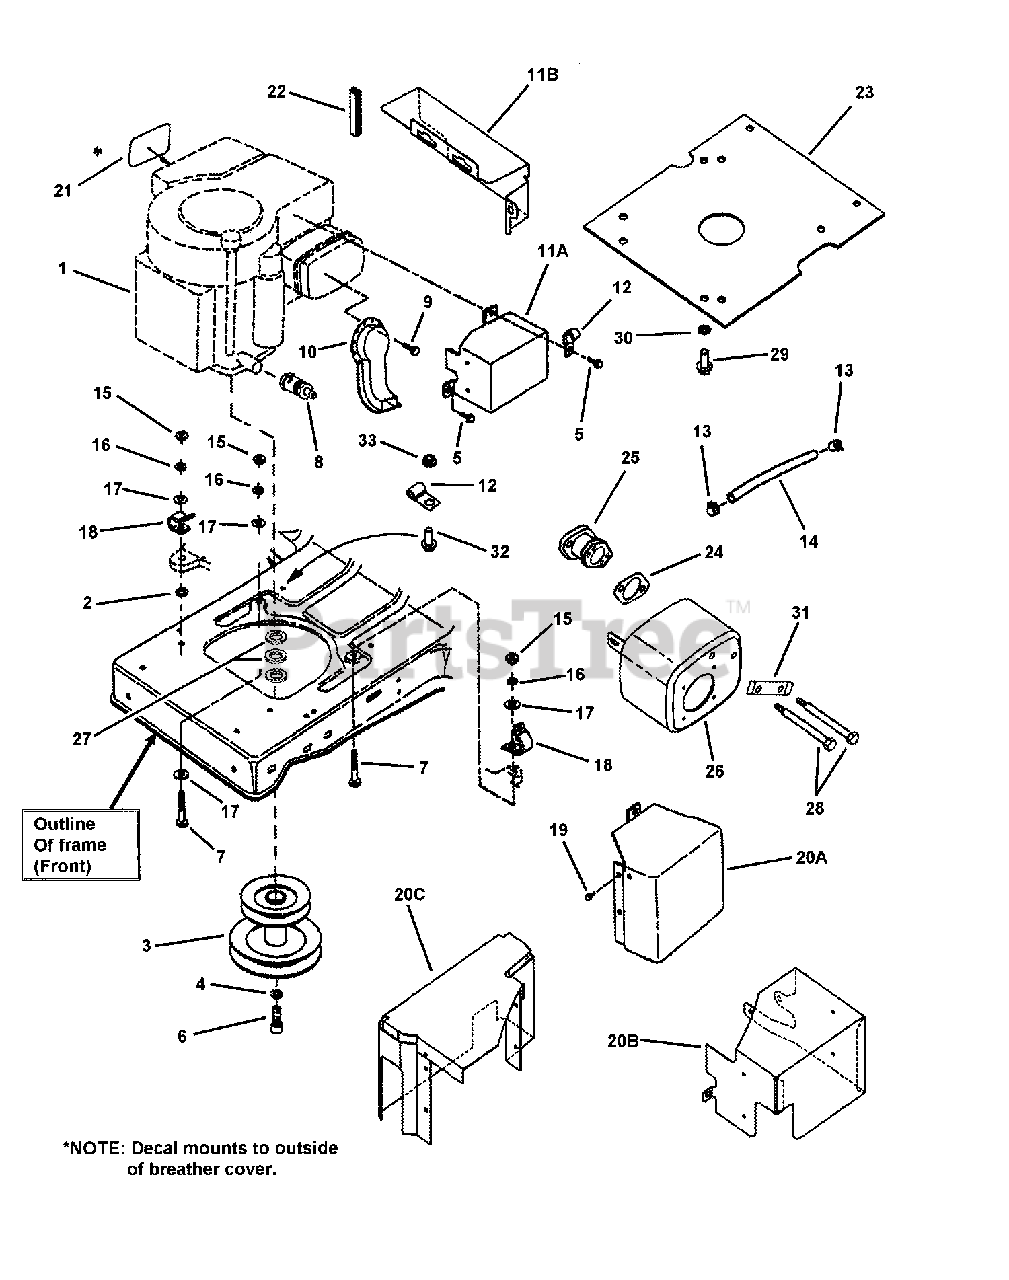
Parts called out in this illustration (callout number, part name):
2	WASHER, 5/16" Internal Tooth Lock
3	ASSEMBLY, Engine Pulley
4	WASHER, 7/16" Split Lock
5	SCREW, 1/4-20 x 1/2" Hex Flange Lock
6	SCREW, 7/16-20 x 1" Socket Head Cap
7	SCREW, 5/16-18 x 1-3/4" Hex Head Cap, GR 5
8	ASSEMBLY, Oil Valve
9	SCREW, #8-18 x 1/2" Hex Head Sheet Metal
10	WELDMENT, Muffler Deflector
11A	HEAT SHIELD, Muffler (weldment)
11B	HEAT SHIELD, Muffler
12	CLIP, "J" Open Type .4 Bundle Dia., .281 Dia. Hole
13	CLAMP, .490 x .31
14	FUEL LINE, 14" long
14	FUEL LINE, 10" long
14	FUEL LINE, 29" long
15	NUT, 5/16-18 Hex, GR 5 or B
16	WASHER, 5/16" Split Lock
17	WASHER, 5/16" Flat
18	HARNESS CLIP, Cushioned
19	SCREW, #10-24 x 5/8" Hex Washer Self-Tap, GR 5
20A	HEAT SHIELD, Muffler
20B	HEAT SHIELD, Muffler
20C	HEAT SHIELD, Muffler
21	DECAL, Warning-Speed Setting 14, 16, & 18 HP ENGINES
22	TRIM-Heat Shield 3" long
23	PLATE, Engine- Briggs Engine
24	GASKET, Exhaust (1.25" I.D.; 1.875" hole centers)
25	ADAPTER, Muffler
26	MUFFLER, 14.5HP Briggs Engine
27	WASHER, .64 x .99 x .05 Flat
28	SHOULDER BOLT, 5/16-18 thread x 4"
29	SCREW, 3/8-16 x 1" Hex Washer Self-Tap
30	WASHER, 5/16" Split Lock
31	SCREW LOCK
32	BOLT, 5/16-18 x 5/8" Hex Flange Lock, GR 5
33	NUT, 5/16-18 Hex Flange Lock, GR 5
